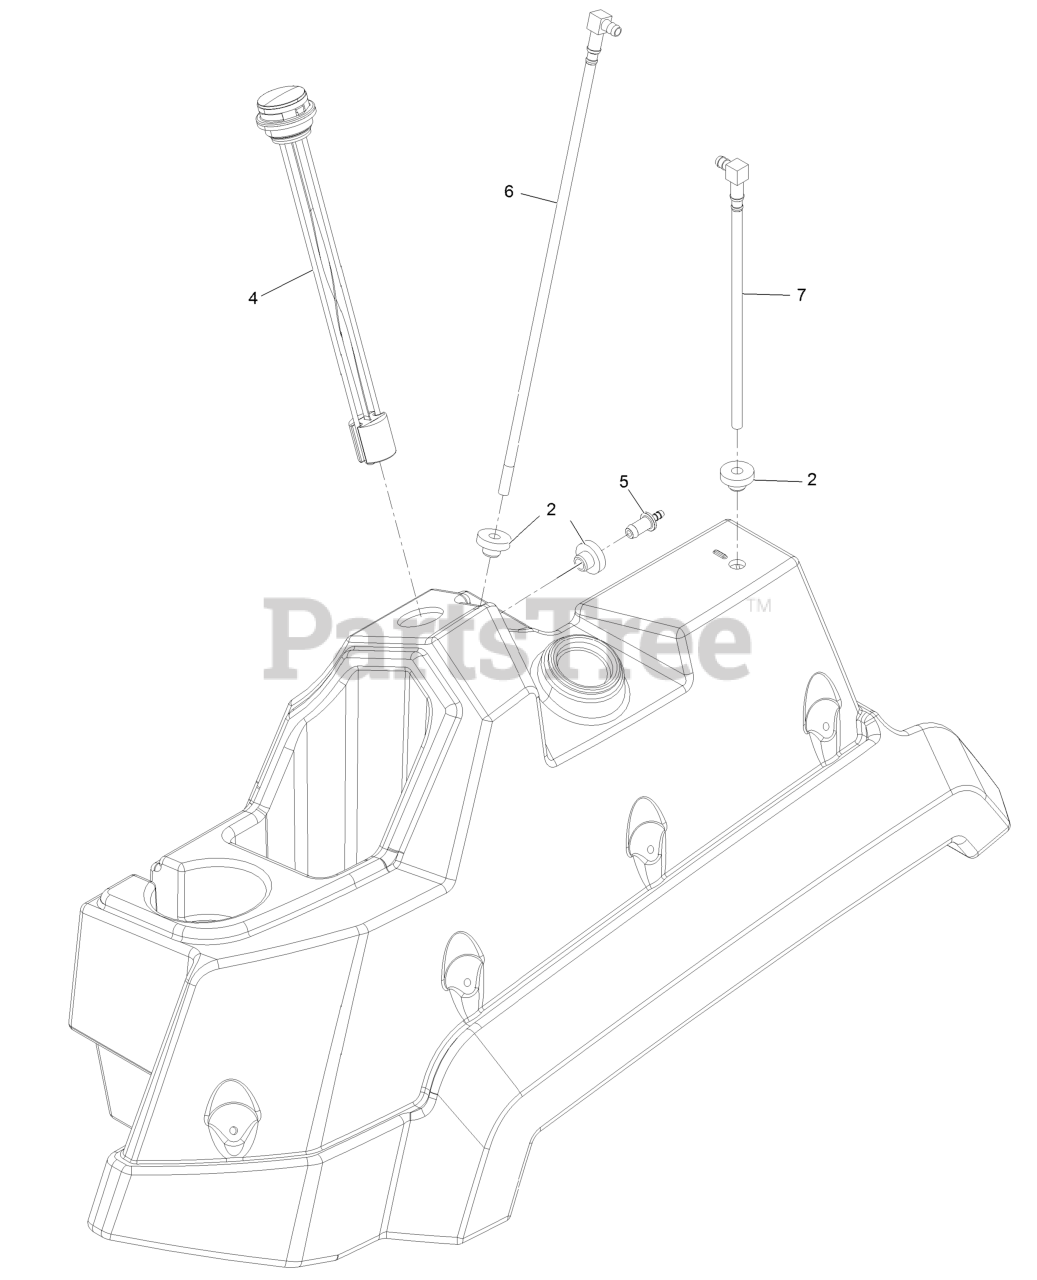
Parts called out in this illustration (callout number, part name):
2	Bushing
4	Gauge-Fuel
5	Fitting-Orifice, Straight
6	Pick-Up-Fuel
7	Return-Fuel
